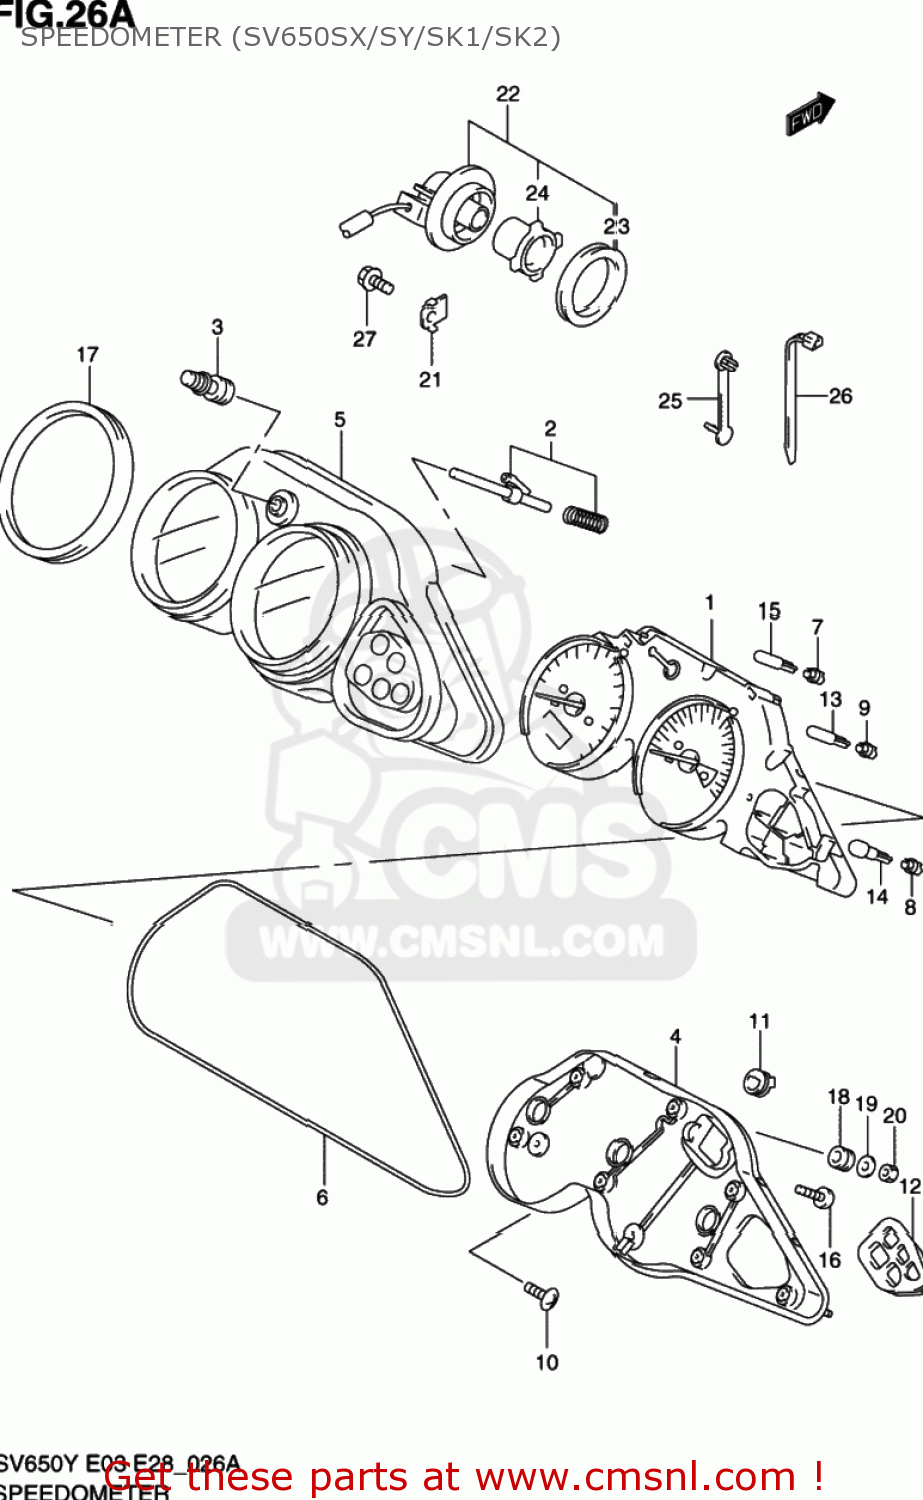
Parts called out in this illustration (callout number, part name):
1	SPEEDOMETER
2	LEVER
3	SWITCH,GUM
4	CASE ASSY
5	VISOR
6	GASKET (NAS)
7	SOCKET,BULB
8	SOCKET
9	SOCKET
10	SCREW(4X14)
11	BLIND,CAP
12	BLIND
13	BULB(12V3W,WB371,T7)
14	BULB(12V1.7W,WB372,T7)
15	BULB(14V,0.84W)
16	SCREW
17	CUSHION
18	CUSHION,METER
19	WASHER(5.5X16X1.2)
20	NUT
21	GUIDE,SENSOR LEAD
22	SENSOR,SPEED
23	SEAL,OIL(44X55X6)
24	ROTOR,SPEEDOMETER
25	CLAMP(L:33)
26	CLAMP(L:145)
27	BOLT
